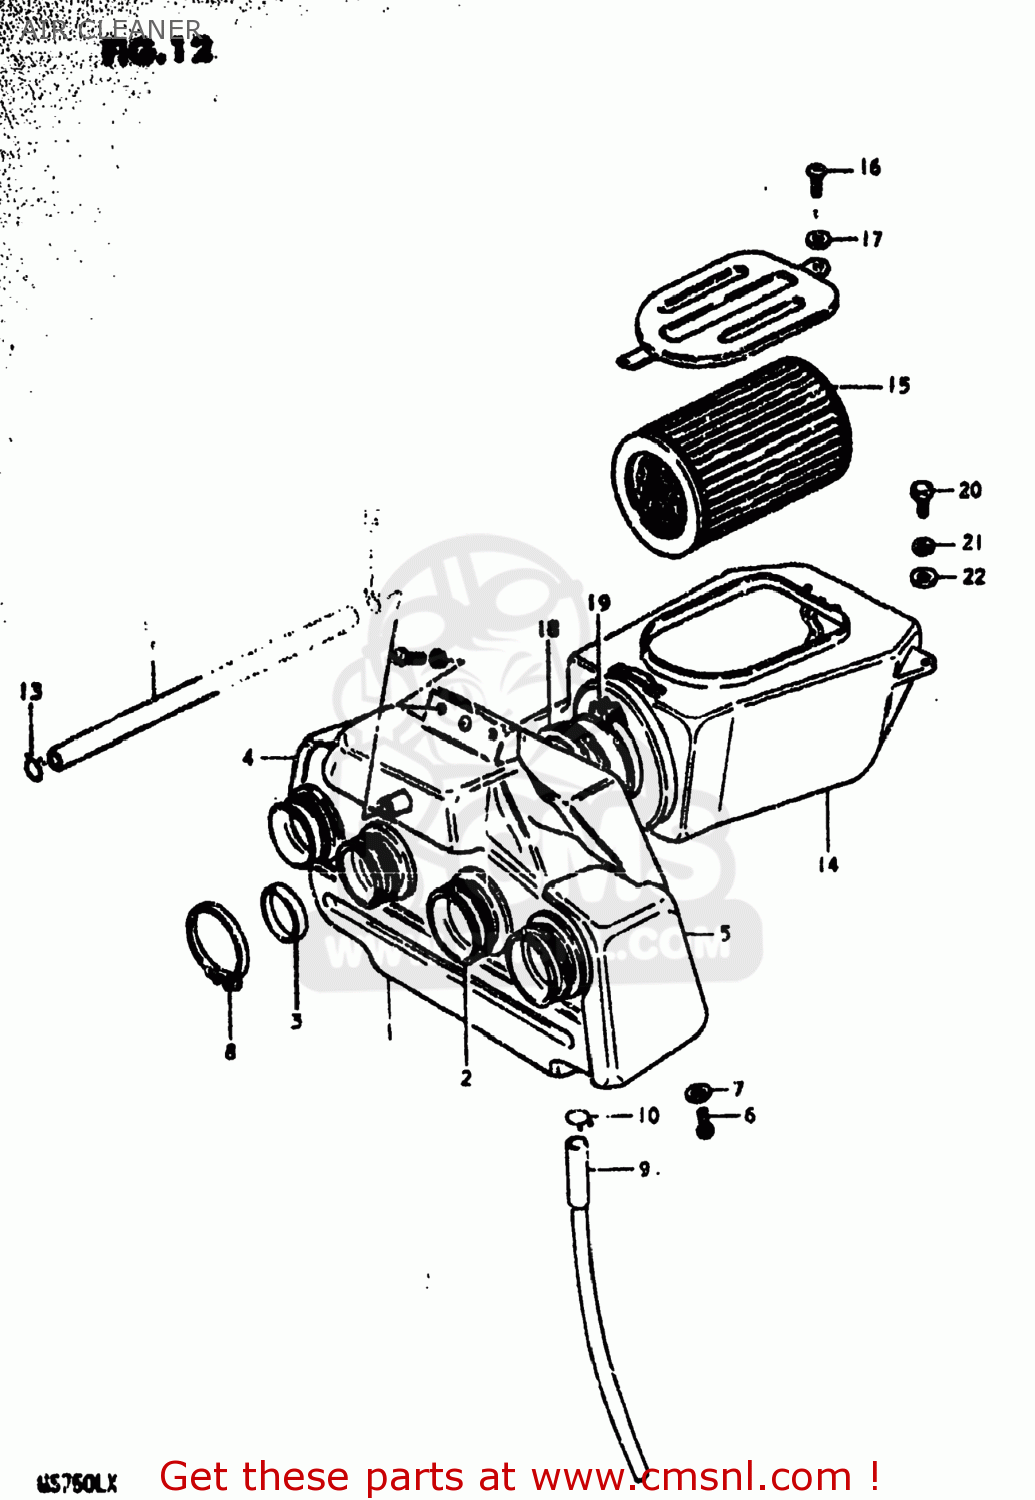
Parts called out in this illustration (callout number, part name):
1	CASE COMP,AIR CLEANER
2	TUBE,AIR CLEANER OUTLET
3	RING,CARBURETOR AIR IN
4	COVER,AIR CLEANER,RIGHT
5	COVER,AIR CLEANER,LEFT
6	SCREW
7	WASHER
8	CLAMP
9	DRAIN TUBE
10	CLIP
11	TUBE,BREATHER
12	CLIP,BREATHER HOSE
13	CLIP
14	CLEANER ASSEMBLY,AIR
15	FILTER,AIR CLEANER
16	SCREW
17	WASHER
18	JOINT,HOSE AIR CLEANER
19	CLAMP
20	BOLT
21	LOCK WASHER
22	WASHER 6MM
